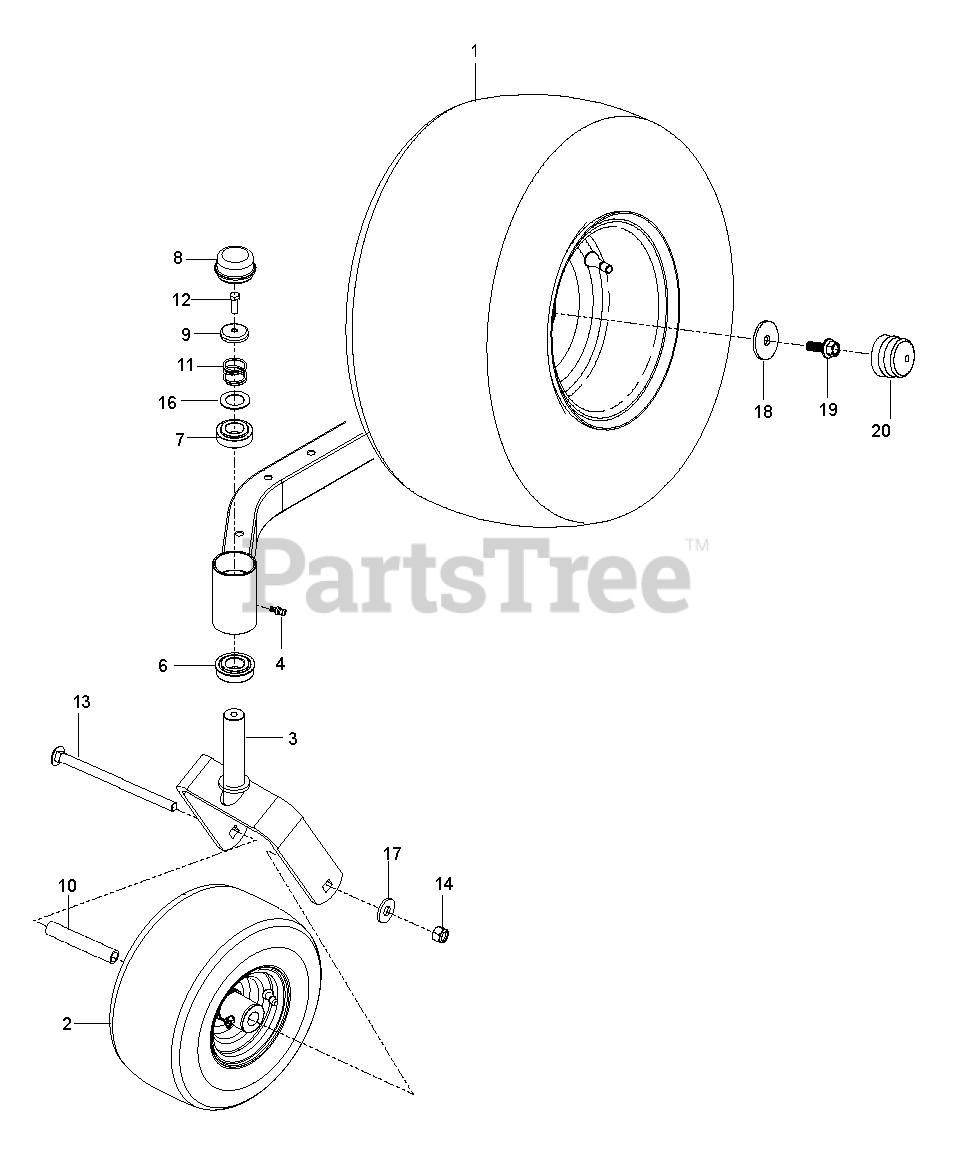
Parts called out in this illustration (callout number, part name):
1	WHEEL.CARLSTAR.18X8.5-8".MS417
2	WHEEL.CARLSTAR.11X4-5".MS417
3	YOKE.CASTER.ORANGE
4	ZERK, 3/16, DRIVE IN
6	BEARING FLANGED
7	BUSHING, CASTER
8	GREASE CAP
9	CASTER.PLUG
11	SPRING, CASTER
12	5/16-18X1 HHB G5W/NY
13	RHSNB 1/2-13 X 6.50 GR5 ZD
14	NUT. 1/2-13 HEX CNTRLK GR 5 ZD
16	WASHER, 1.025 ID X 1.64
17	WASHER.9/16 X 1 3/8 X 12 GA.
18	WASHER ROUND 3/8 X 1-5/8 X.125
19	HHFS 3/8-16 X 1 GRD 5 ZD
20	CAP, AXLE BLK
